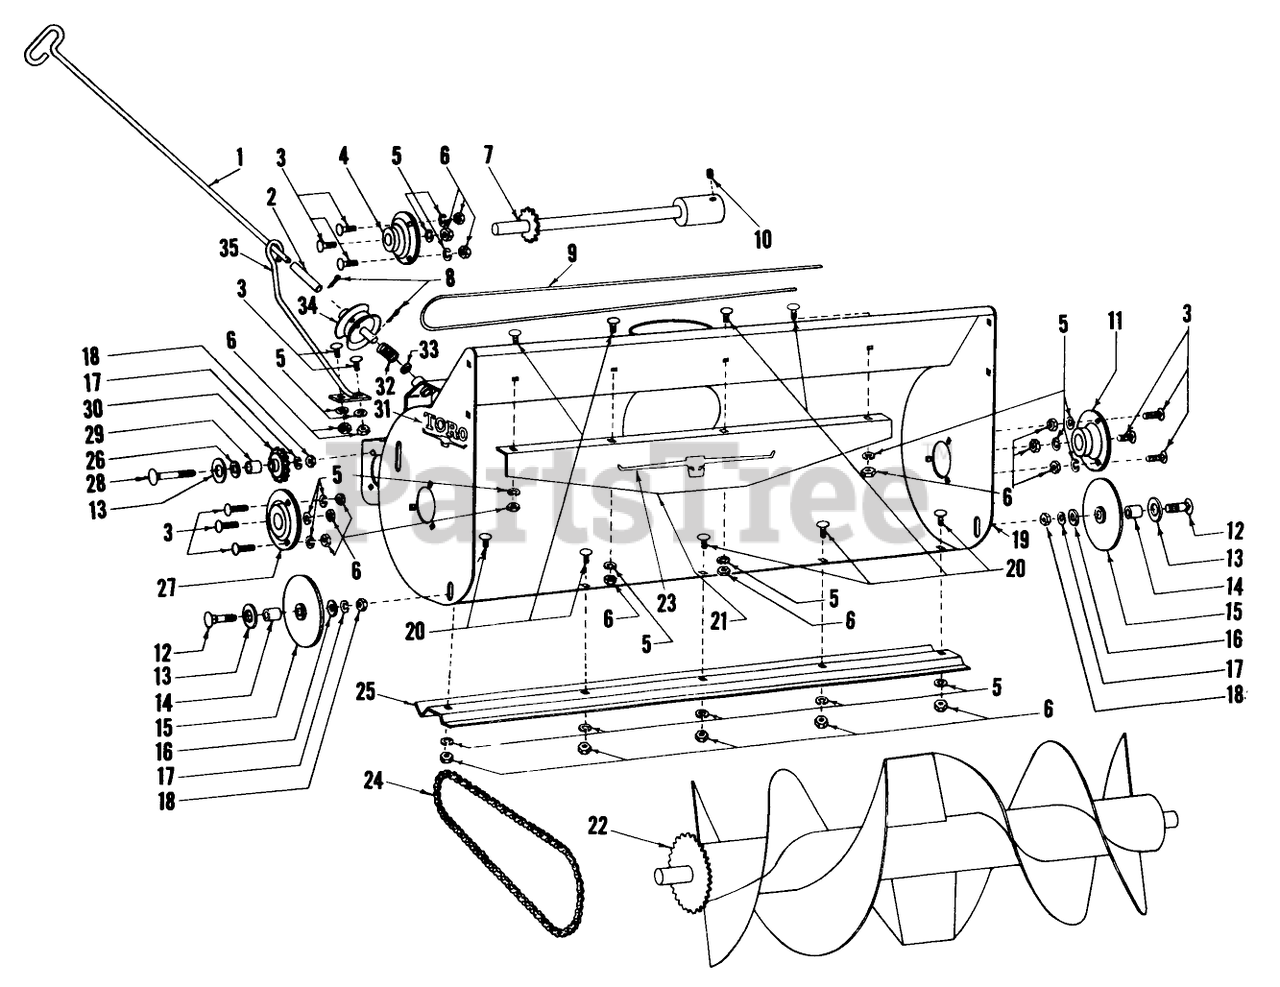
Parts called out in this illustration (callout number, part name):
1	Rod Chute Handle
2	Sleeve
3	Carriage Bolt
4	Bearing w/Setscrew
7	Chain DriveShaft Assy
8	Cotter Pin
9	Control Cable
10	Set Screw
11	Bearing w/Setscrew
12	Capscrew
14	Bushing
15	Guide Wheel
17	Washer
19	Housing
20	Carriage Bolt
21	Snow Shield
22	Rotor Assembly
23	Decal
24	Roller Chain
25	Blade-Scraper
27	Bearing w/Setscrew
28	Carriage Bolt
29	Spacer
30	Chain Idler
31	Decal
32	Compression Spring
33	Washer
34	Chute Control
35	Chute Handle Support
